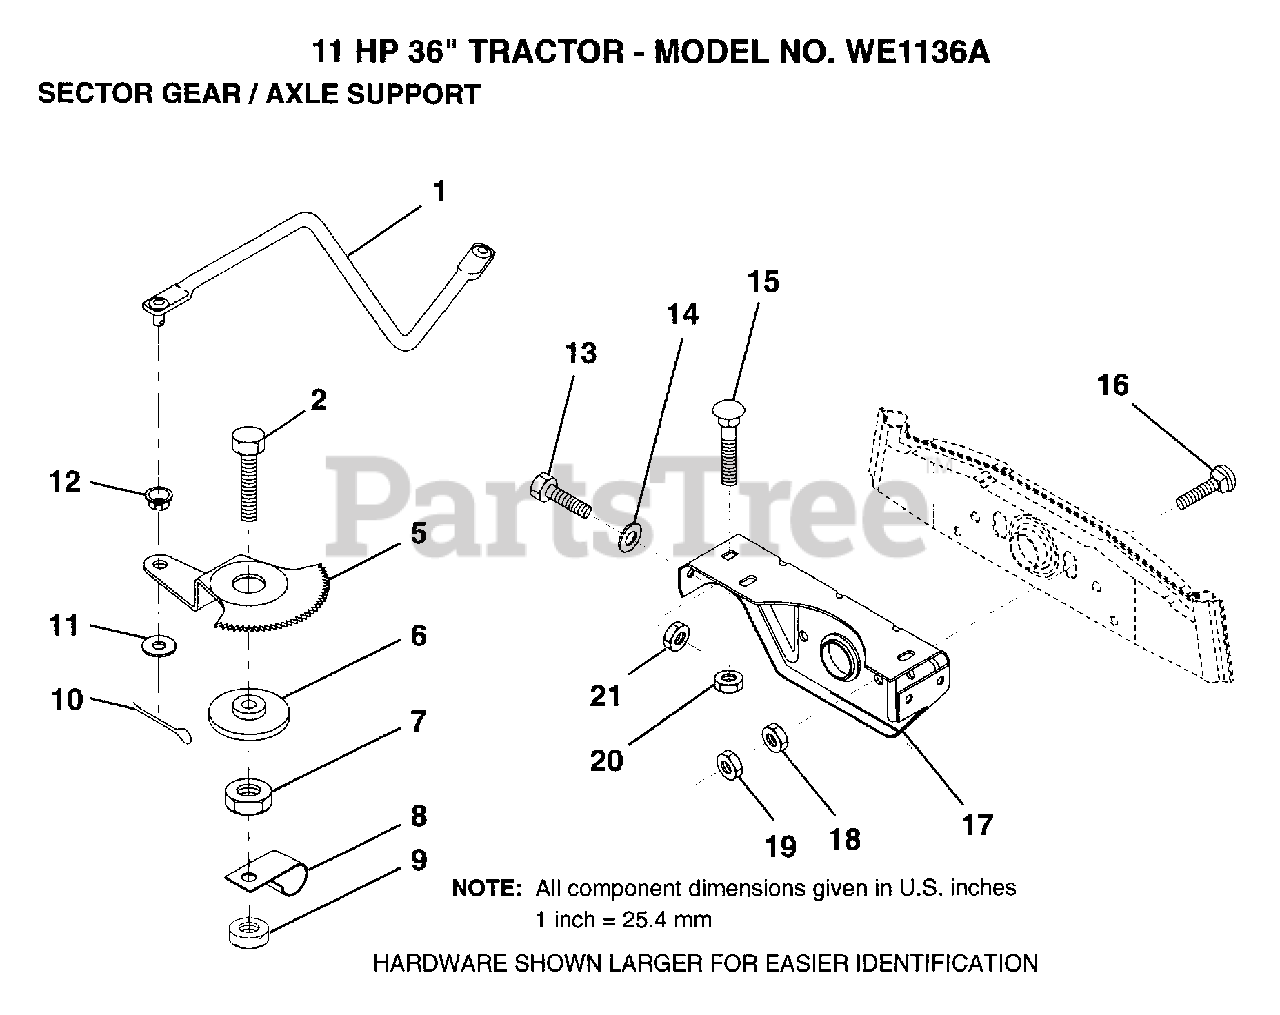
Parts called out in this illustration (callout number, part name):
1	DRAG LINK
2	"BOLT,HEX"
5	GEAR SECTOR
6	BUSHING
7	NUT
8	CLIP INSULATOR
9	NUT LTV
10	COTTER PIN
11	WASHER
12	BUSHING.DRAGLINK
13	BOLT
14	WASHER
15	BOLT
16	BOLT
17	"SUPT,FRT AXLE"
18	NUT.HEX.3/8-16UNC
19	LOCKNUT
